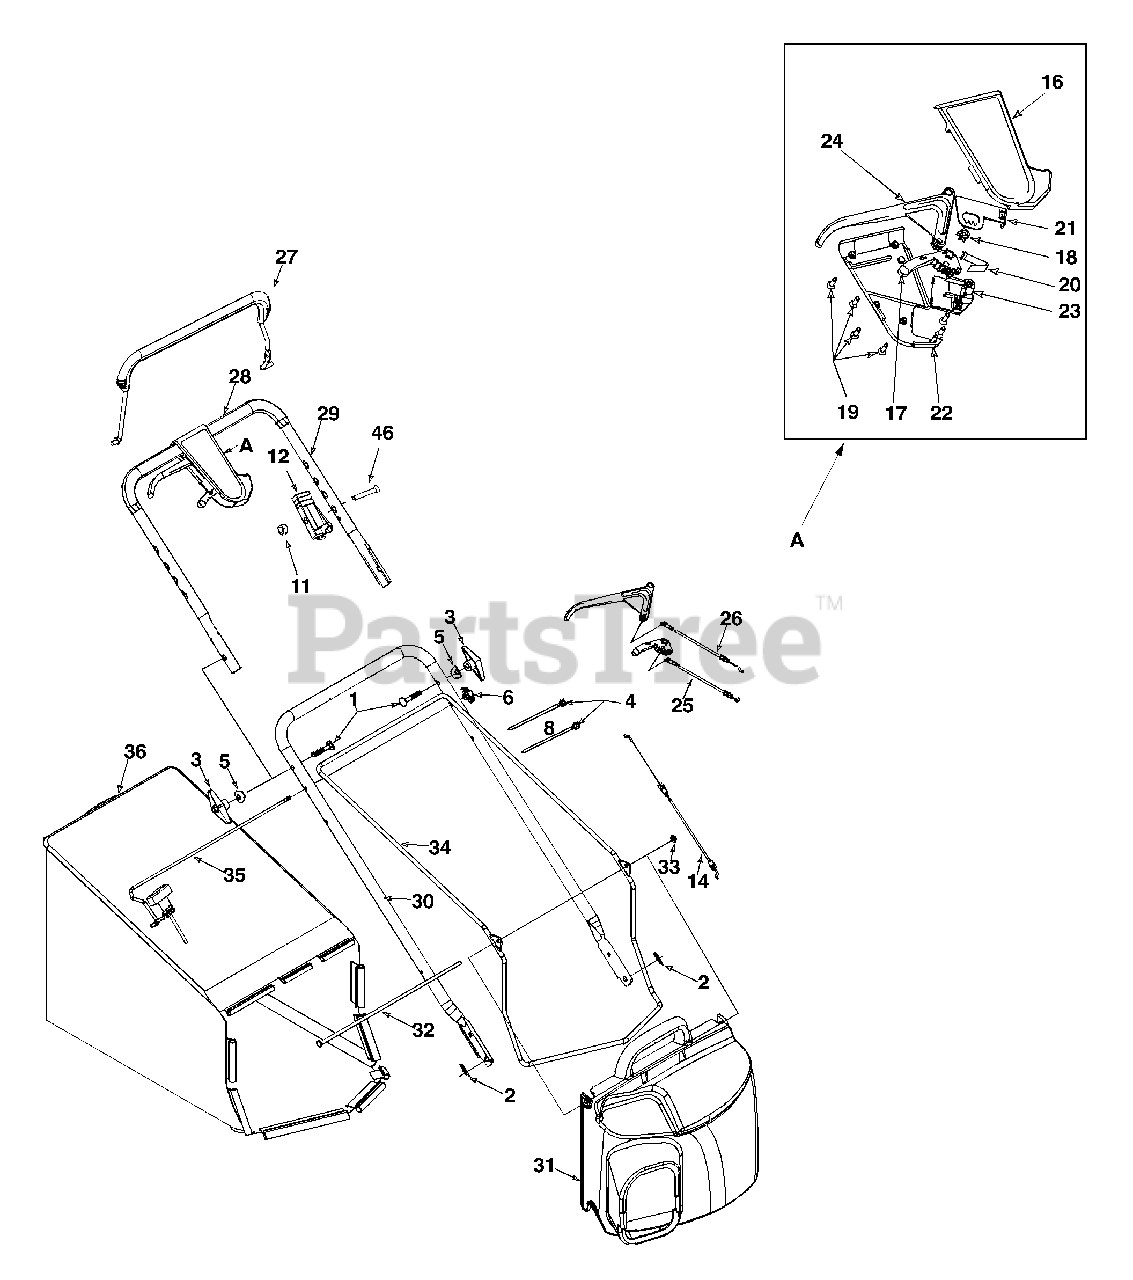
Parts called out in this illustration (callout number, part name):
1	Bolt Cur. Carr. 5/16-18 x 2.0
2	Cotter Pin .072 x 1.12 Lg.
3	Knob Assembly 5/16-18
4	Strap 4.3" Lg.
5	Wash. Sad..320 ID x.830 OD
6	Handle Knob 1/4-20
11	Nut 1/4-20 Top Lock Nut Insert
12	Control Cable Housing
14	Control Cable 44" Lg.
16	Upper Control Housing
17	6-Speed Shift Lever
18	Gear Insert
19	C Sunk Tap Screw #10-16x.625
20	Shift Lever Spring
21	6 Spd. Rack Cable Brkt.
22	Lower Control Housing
23	Cable Mounting Cap
24	Control Lever
25	6 Spd. Cable
26	Self Prop. Cable, 52"
27	Control Handle
28	Foam Grip (2 required)
31	Grass Bag Cover
46	Hex Bolt 1/4-20 x 1.3"
